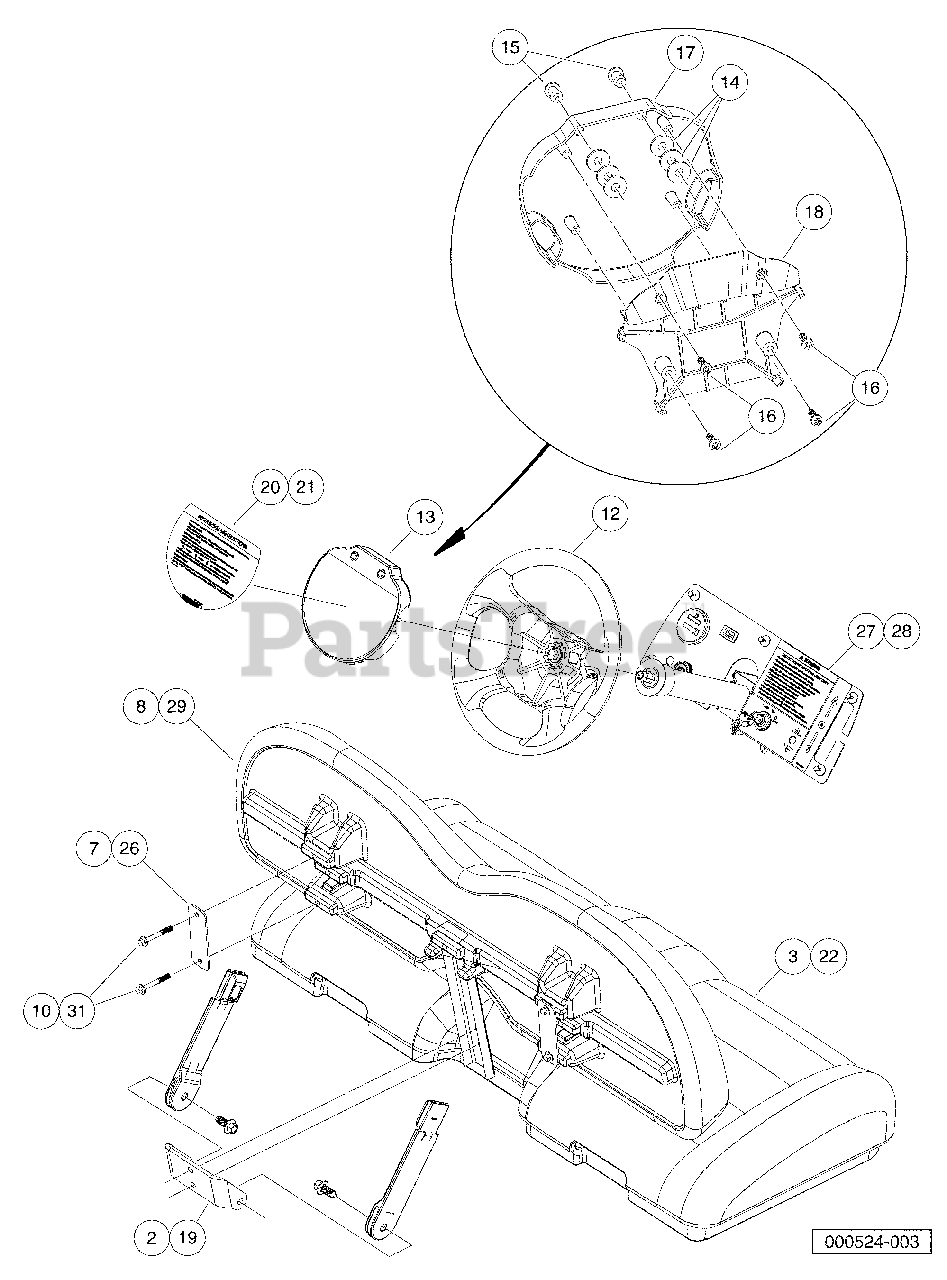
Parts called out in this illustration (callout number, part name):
1	Kit, Bench Seat, Seat Only
2	Bracket, Seat Belt, Bench
3	Asm, Seat Bottom, Bench, Gray (includes items 4 through 6)
4	Hinge Plate
5	Asm, Seat Bottom, Bench.
6	Bolt Flg Blk, M8 X 25, Loctite
7	Bracket, Seat Back, AWD
8	Seat Back, Bench, Gray
9	Instructions, Bench Seat
10	Bolt Flg Blk, M8 X 55, Loctite
11	Kit, Bench Seat, Complete
12	Steering Wheel, Comfort Grip, Hex.
13	Center, Plate, Steering Wheel
14	Washer, 5/16 Flat
15	Blind Rivet, Push Type
16	Part Number for Club Car part number 102296020Screw, Torx Pan Hd Pt, M6 X
17	Scorecard Plate, Comfort Grip
18	Scorecard Back Plate
19	Bracket, Seat Belt, Bench
20	Decal, Oper Instr, Awd Se Dsl.
21	Decal, Oper Instr, Awd Se Gas
22	Asm, Seat Bottom, Bench, Gray
23	Hinge Plate
24	Asm, Seat Bottom, Bench.
25	Bolt Flg Blk, M8 X 25, Loctite
26	Bracket, Seat Back, AWD
27	Decal, Warning, Iinstrument Panel, AWD Gas
28	Decal, Warning, Iinstrument Panel, AWD Diesel
29	Seat Back, Bench, Gray
30	Instructions, Bench Seat
31	Bolt Flg Blk, M8 X 55, Loctite
